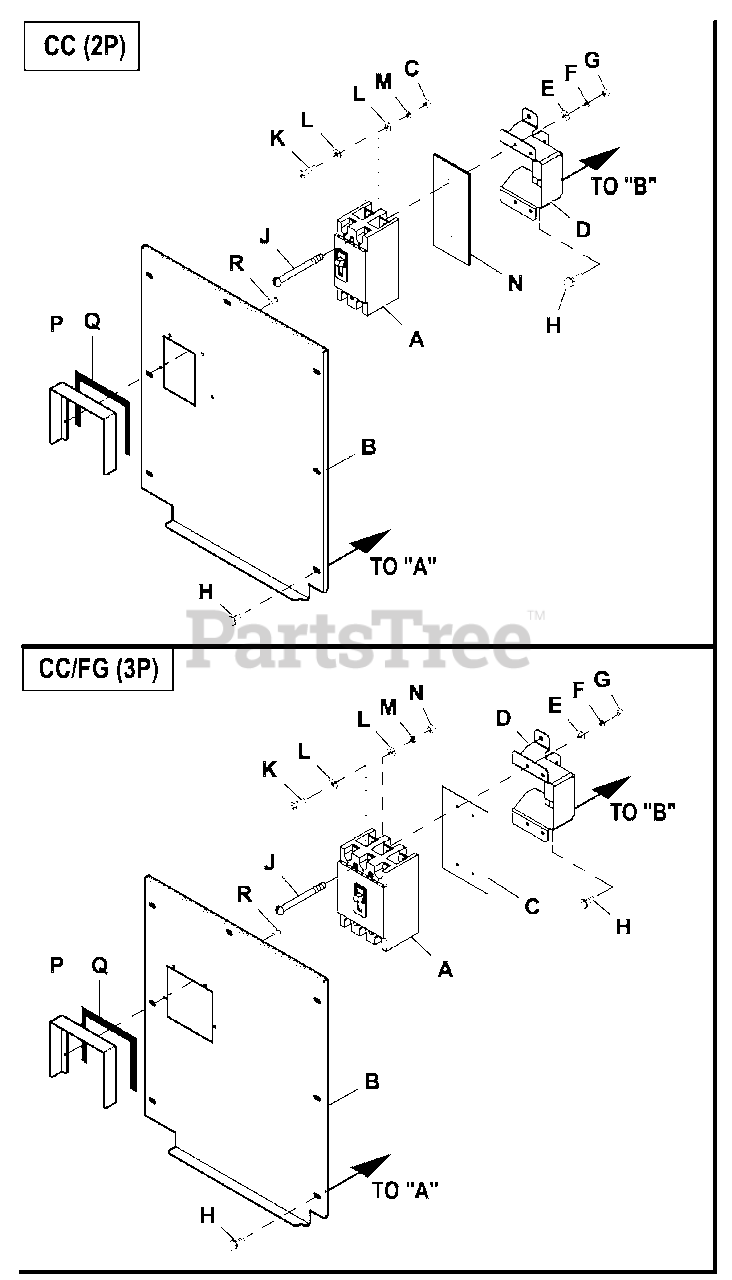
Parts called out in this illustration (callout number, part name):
A	CB0100A2P 240VECC LL
B	COVER CB E CC 2P C1 CONBOX
C	NUT HEX M5-0.8 G8 CLEAR ZINC
D	CIRCUIT BREAKER SUPPORT (CC)
E	WASHER FLAT #8 ZINC
F	WASHER LOCK #8-M4
G	NUT HEX #8-32 STEEL
H	SCREW HWHT M6-1 X 16 N WA Z/JS
J	SCREW RHM #8-32X3-1/4
K	SCREW PPHM M5-0.8 X 12 ZNC
L	WASHER FLAT #10 ZINC
M	WASHER LOCK M5
N	INSULATOR CB 2P E TYPE CC
P	SHIELD CB HANDLE CONBOX
Q	TAPE ELEC 1/2 FOAM
R	RIVET POP .125 X .275 SS
A	CB 0100 3P 240V E CC LL
B	CB COVER E CC/FG 3P C1 CONBOX
C	INSULATOR CB 3P E TYPE CC/FG
F	WASHER LOCK#8-M4
J	SCREW PPHM #8-32 X 1-3/4 ZINC (CC)
N	NUT HEX M5-0.8 G8 CLEAR ZINC
